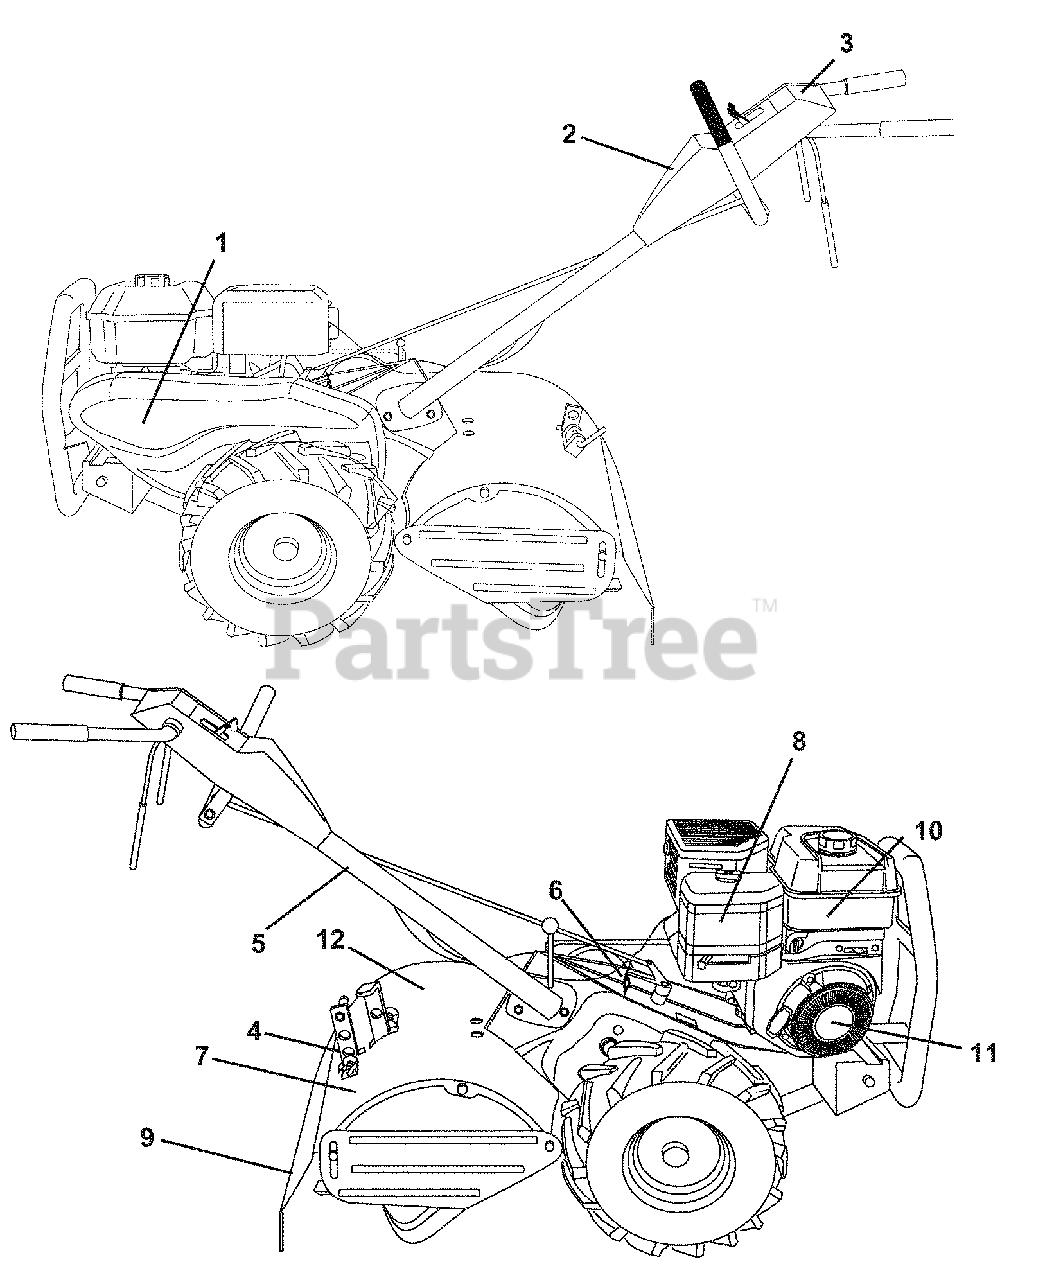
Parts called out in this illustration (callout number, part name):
1	Decal, Belt Guard
2	Decal, Console
3	Decal, Console
4	Decal, Tine Shield
5	Decal, Hand Placement
6	Decal, Shift Indicator
7	Decal, Reverse
8	Decal, Engine B&S
9	Decal, Warning, Rotating Tines
10	Decal, Engine Intek REF
11	Decal, Rewind Intek
12	Decal, Forward
